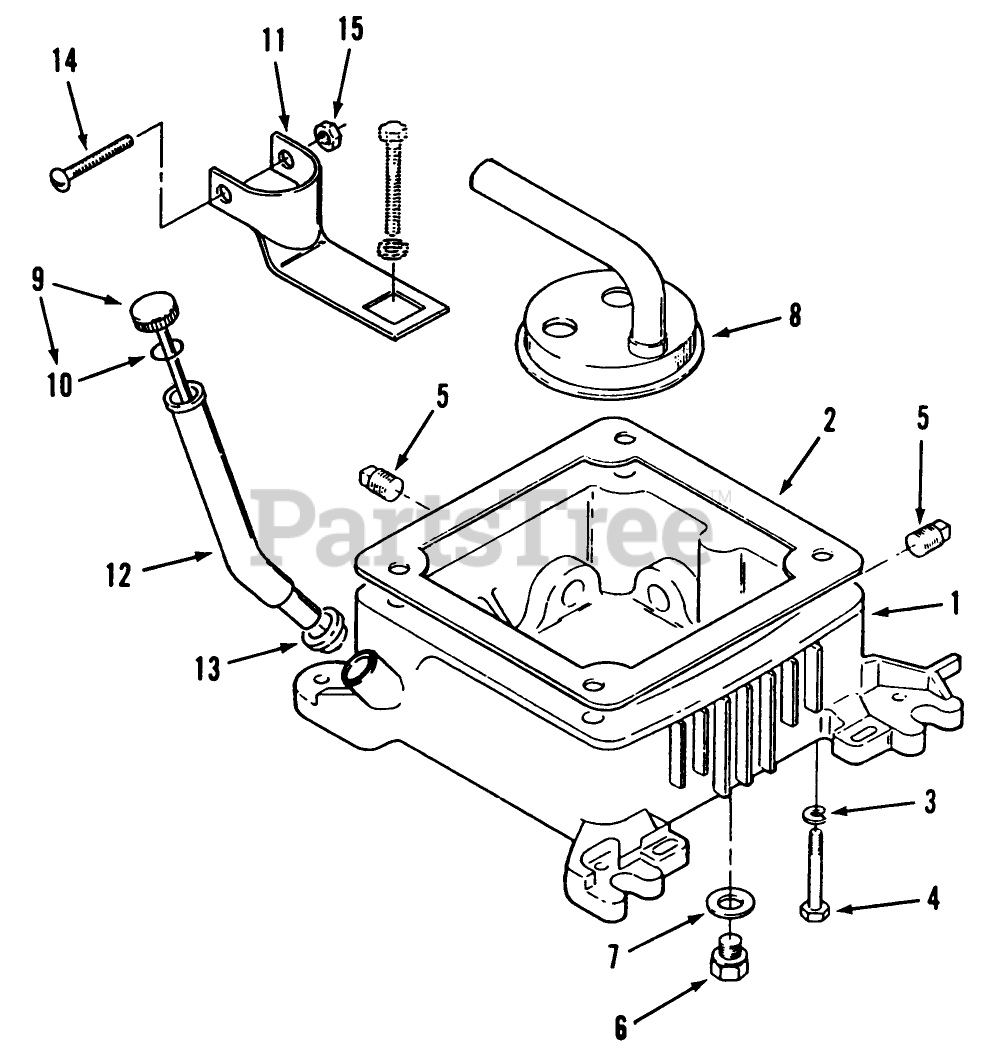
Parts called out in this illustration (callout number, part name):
1	OIL BASE ASSY
3	WASHER-FLAT
5	PLUG - SQUARE HEAD
